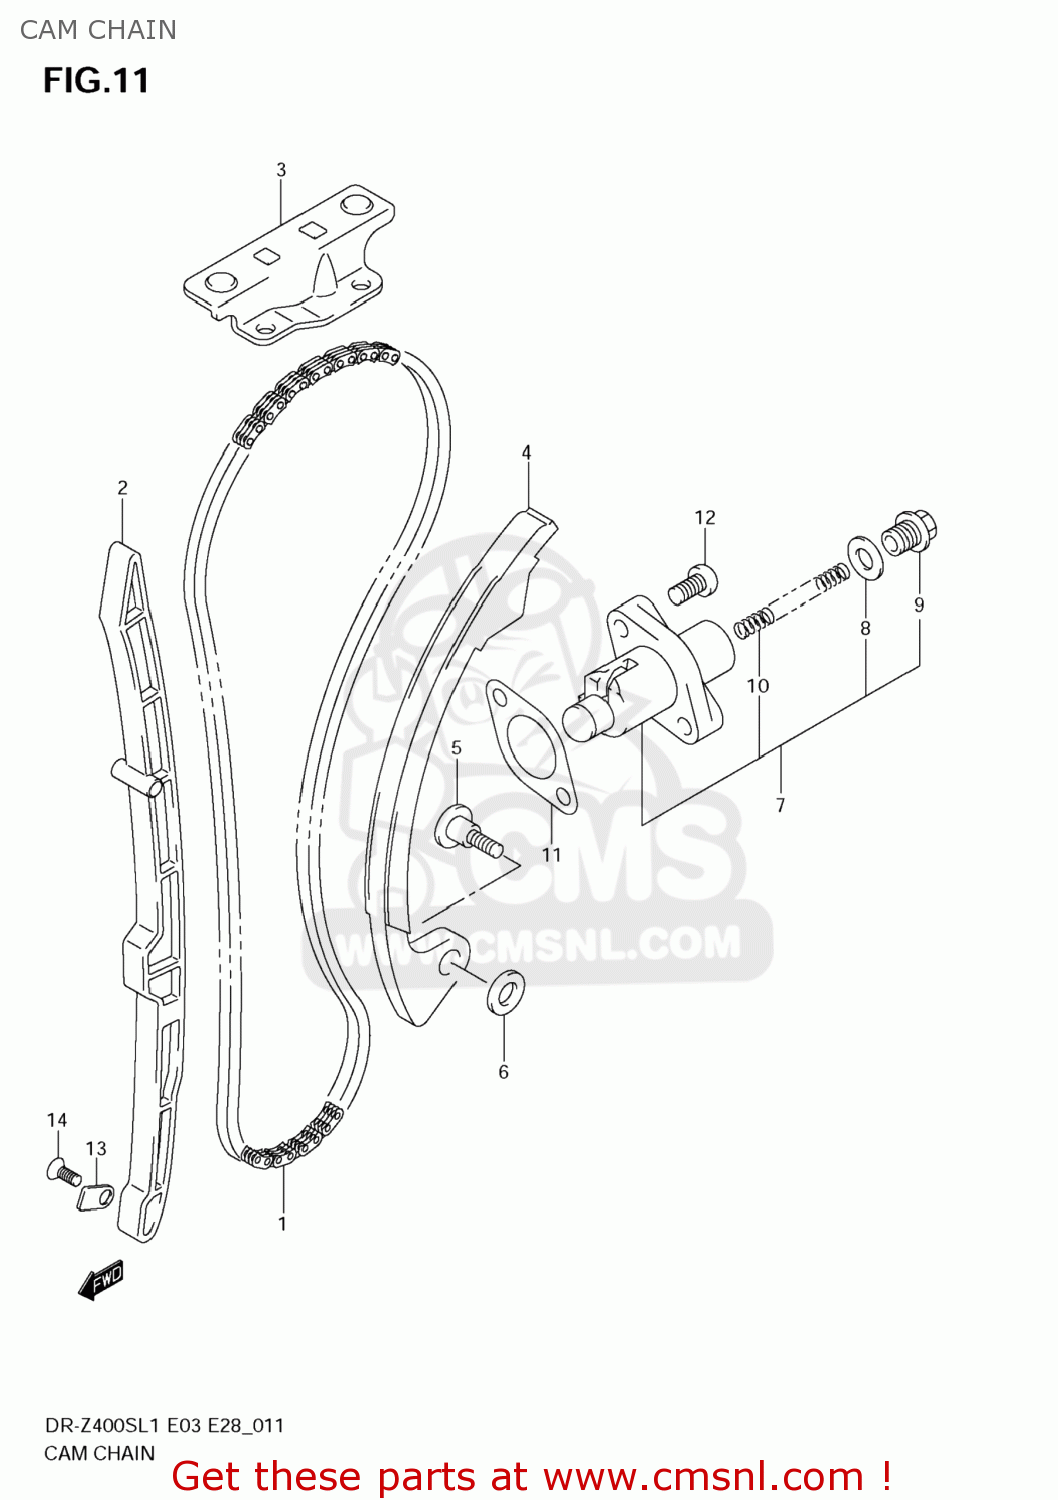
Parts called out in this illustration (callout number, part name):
1	CHAIN,CAMSHAFT DRIVE
2	GUIDE,CAM CHAIN NO.1
3	GUIDE,CAM CHAIN NO.2
4	TENSIONER,CAM CHAIN
5	BOLT,CAM CHAIN TENSIONER
6	WASHER
7	ADJUSTER ASSY,TENSIONER
8	GASKET,TENSIONER ADJUSTER (NAS)
9	PLUG,FR TENSIONER ADJ
10	SPRING
11	GASKET,TENSIONER ADJUSTER (NAS)
12	BOLT
13	RETAINER,CAM CHAIN GUIDE NO.1
14	SCREW(6X12)
